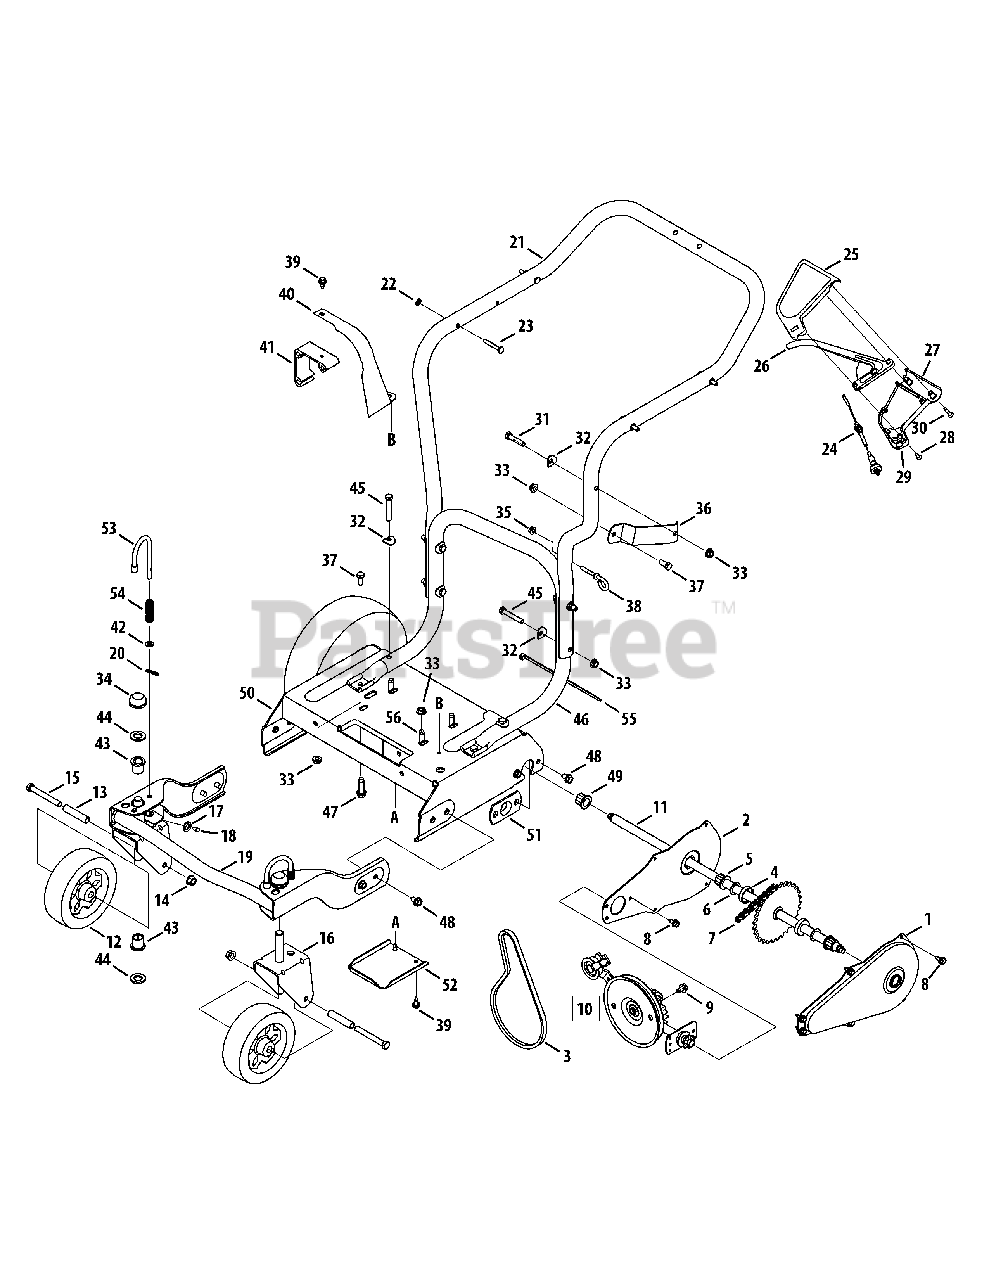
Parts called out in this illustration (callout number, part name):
1	Chain Case - LH
2	Chain Case - RH
5	Hex Flange Bearing
6	Flat Washer
8	TT Screw, 1/4-14 x 0.625"
9	Hex Washer Screw, 5/16
10	Chipper Shredder Trans. Ass’y.
11	Axle Assembly
12	Wheel, 6.0 x 2.0
14	Flange Lock Nut, 3/8-16
15	Hex Cap Screw, 3/8-16 x 3.0
16	Bracket Assembly
17	Flat Washer, .203 ID x.403 OD
18	Grease Fitting, 3/16
19	Bracket Assembly
20	Cotter Pin
23	Stud Pin, .250 x 1.75
24	Clutch Cable - 56"
25	Upper Clutch Cover
26	Drive Lever
27	Lower Clutch Cover
28	Screw, #10-12 x.750
29	Mounting Cable Cap
30	Screw, #10-16 x 1.25
31	Hex Cap Screw, 5/16-18 x 1.50
32	Shldr. Washer, .320 ID x.93 OD
33	Hex Flange Lock Nut, 5/16-18
35	Hex Nut, 1/4-28
36	Discharge Chute Bracket
37	Hex Cap Screw, 5/16-18 x.75
39	Hex Washer Screw, 1/4-14 x.625
40	Belt Cover
41	Engine Mounting Adapter
42	Flat Washer, .330 ID x.630 OD
43	Flange Bearing, .632 ID
44	Flat Washer, 5/8 ID x 1.0 OD
45	Hex Cap Screw, 5/16-18 x 1.75
46	Lower Push Handle
47	Screw, 3/8-16 x 1.25
48	Hex Wash. Screw, 5/16-18 x.625
49	Hex Flange Bearing, .631 x.720
50	Frame Assembly
52	Transmission Cover
54	Compression Spring
55	Cable Tie
56	Hex Cap Screw, 5/16-18 x 1.25
